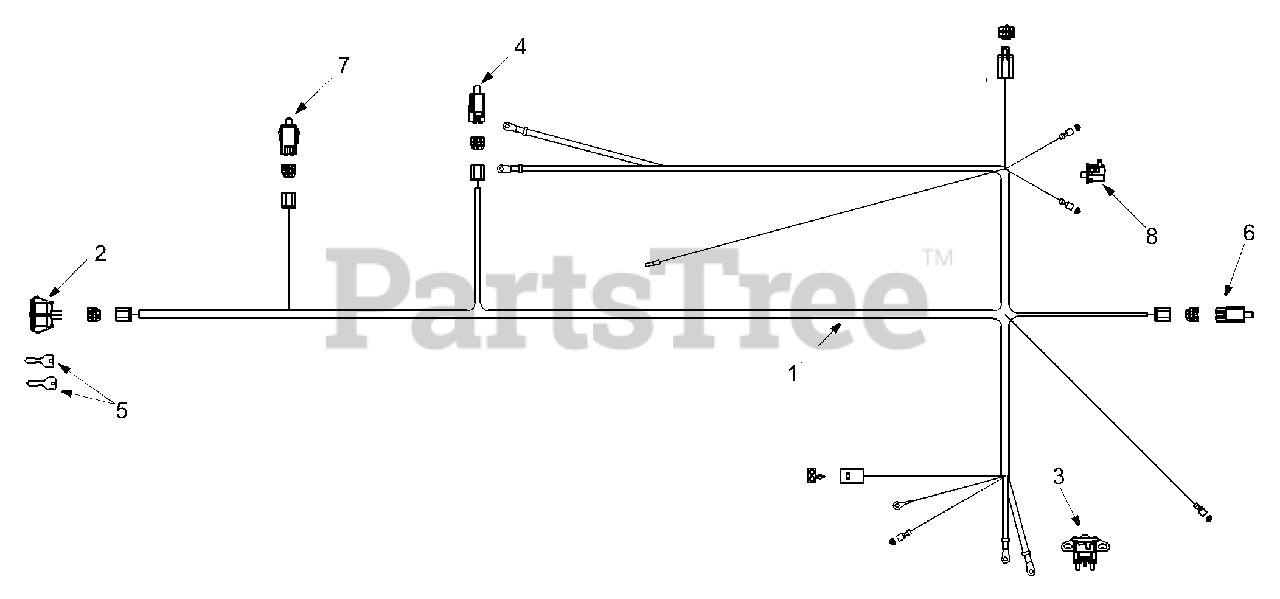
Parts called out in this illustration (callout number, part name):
1	Harness Assembly
2	Key Switch
3	Solenoid: 12 V. 100 amp.
4	Interlock Switch
5	Key
6	Switch: Plgr N.C./N.C.
7	Switch: Plgr N.O./N.C.
8	Switch: Mt. Snap N.C.
